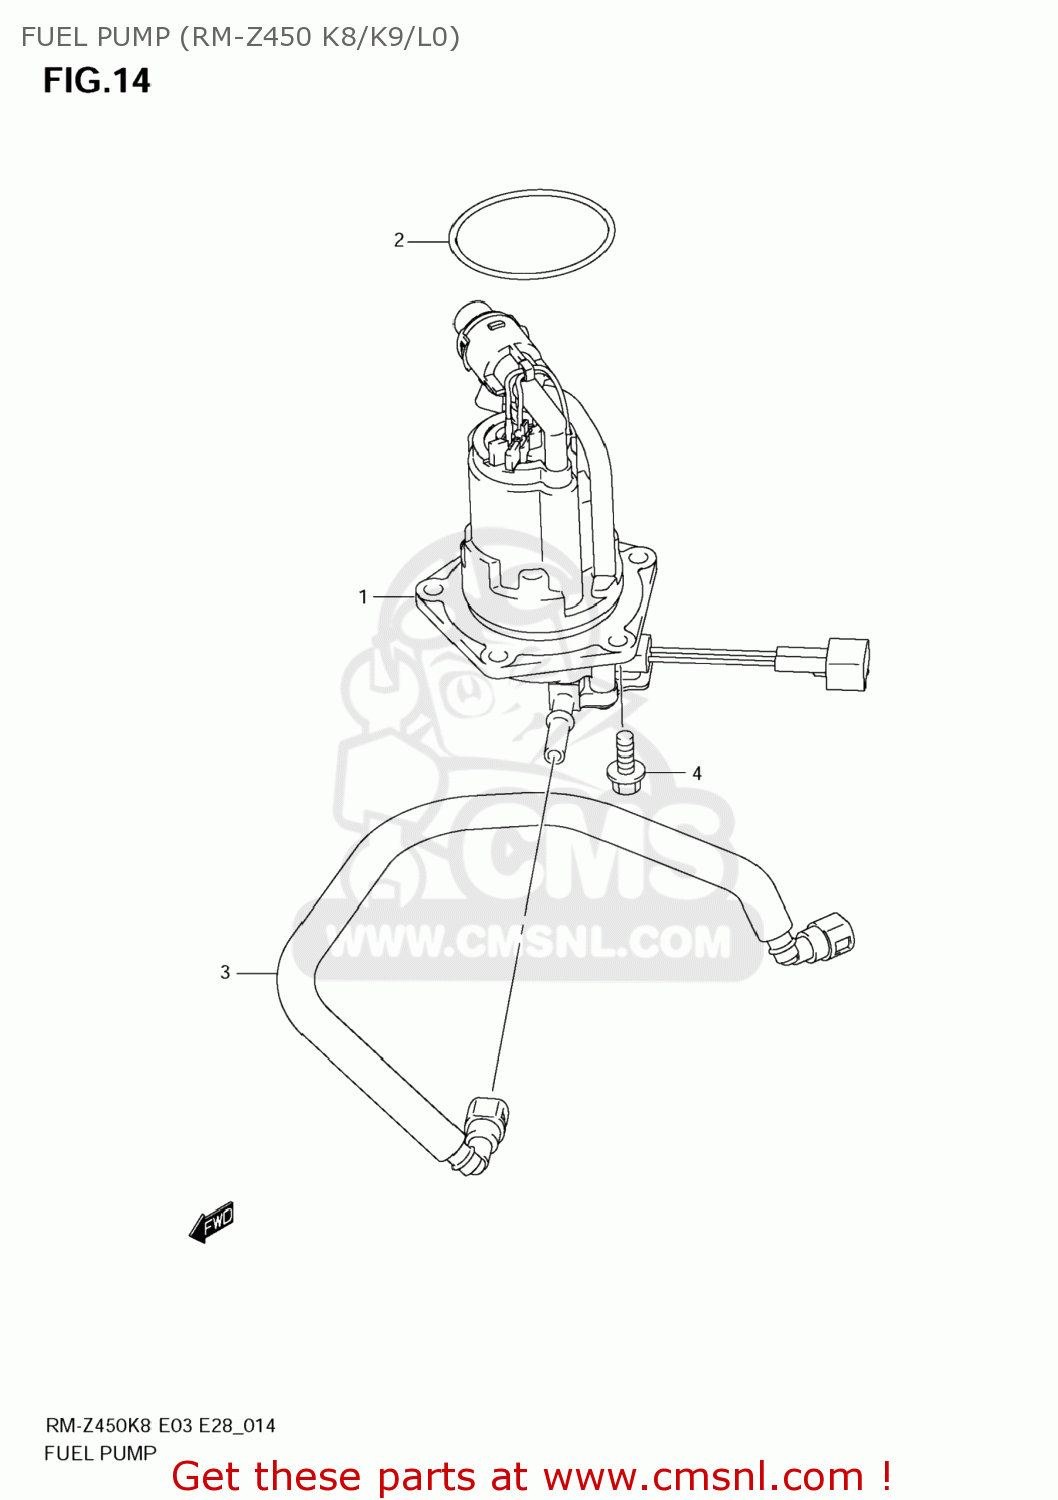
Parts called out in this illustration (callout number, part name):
1	PUMP ASSY,FUEL
2	O RING
3	HOSE,FUEL
4	BOLT
